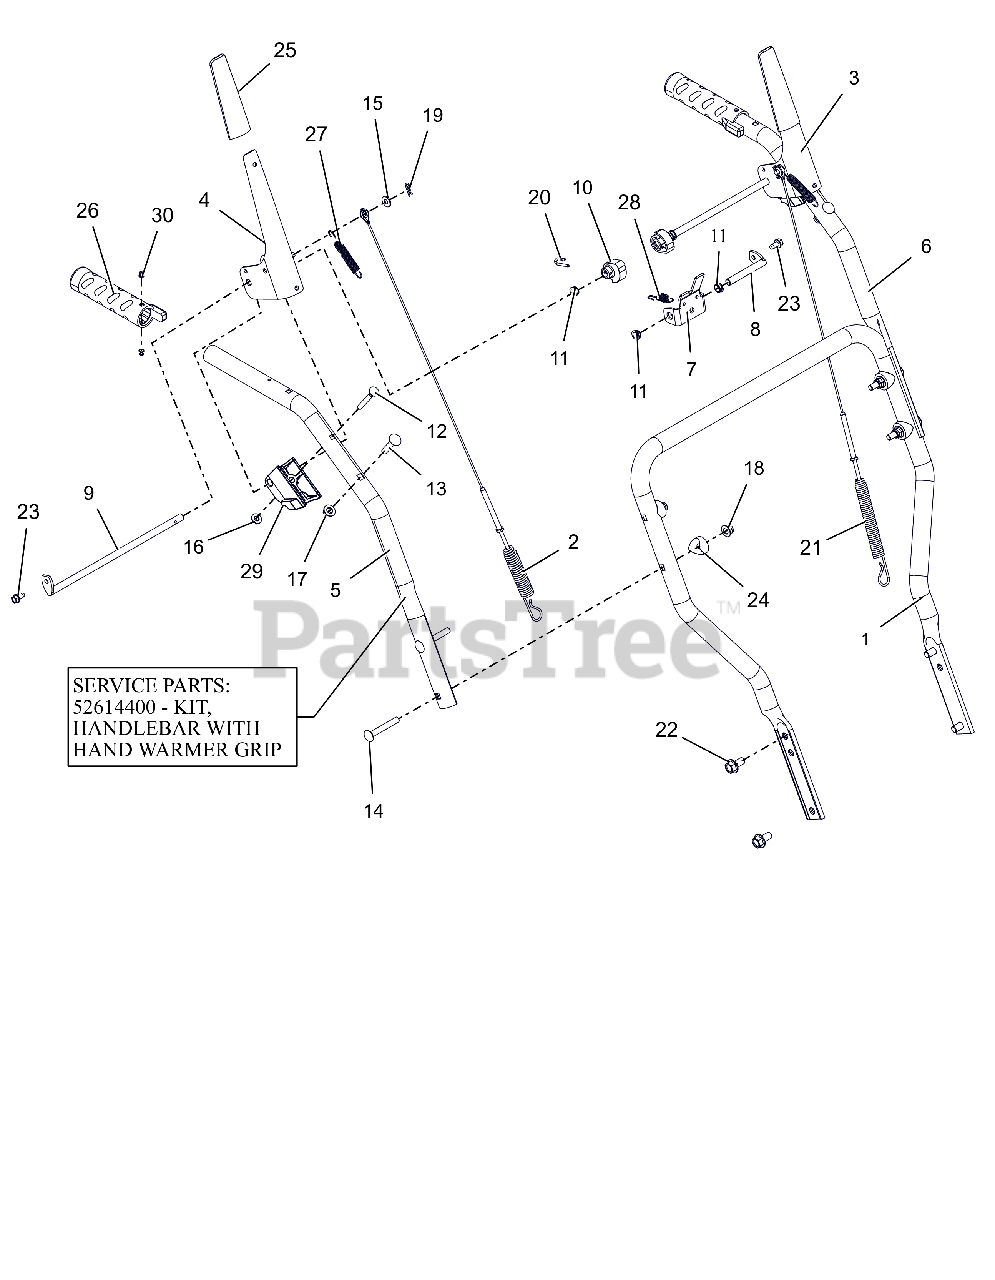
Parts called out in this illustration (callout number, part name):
1	HANDLEBAR, LOWER
2	CABLE, AUGER (DELUXE & PRO)
3	LEVER, CLUTCH-LH
4	LEVER, CLUTCH-RH
5	HANDLEBAR, UPPER - RH
5	KIT, HANDLEBAR HW RH
6	HANDLEBAR, UPPER - LH
6	KIT, HANDLEBAR HW LH
7	BRACKET, INTERLOCK ARM
8	ROD, PIVOT - INTERLOCK
9	ROD, PADDLE MOUNT - PRO
10	CAM, INTERLOCK
11	BUSHING, POLYLINER-.38 SNAPIN
12	BLT-RDHDXLSQNK .25-20X2.0 G5YZ
13	@BLT-RDHDSQNK .31-18X1.50 G5YZ
14	@BLT-RDHDSQNK .31-18X2.25 G5YZ
15	@WSHR-FL-STL.281X.62X.065 YWZC
16	@NUT-LK-CTR-FLG .25-20 YWZC
17	@NUT-LK-TOP-FLG .31-18 YWZC
18	@NUT-LK-NYL-FLG .31-18 YWZC
19	PIN-HAIR INT .06X.18X.77
20	PIN, SPRING CLIP
21	CABLE, UPPER TRACTION
22	BLT-SERHFWH .38-16X.75 YWZC
23	SCR-TAP .25-20X.50 HWH TR YWZ
24	SPACER, HANDLEBAR
25	SLEEVE, CLUTCH PADDLE-GRAY
26	GRIP,HEATED HANDLE-GRAY
27	SPRING, EXTENSION
28	SPRING-EXT .047X.438X1.45
29	BLOCK, CLUTCH PADDLE
30	RVT-POP #43 .125X.313 STL ZINC
